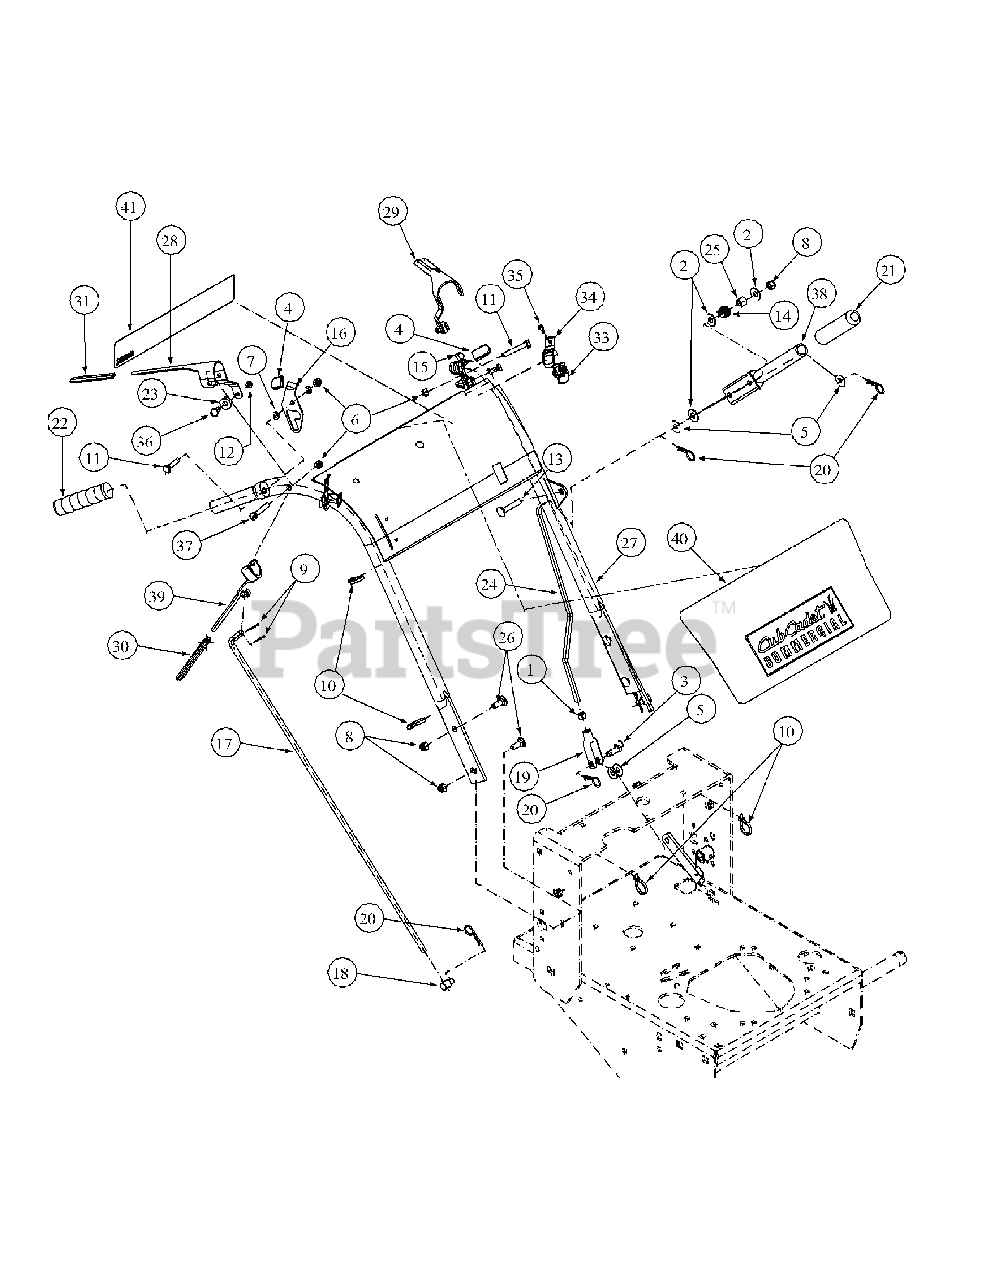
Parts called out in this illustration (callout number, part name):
1	Hex Nut, 3/8-16
2	Flat Washer, 3/8 Zinc
3	Clevis Pin, 3/8 x 1-1/8 Zinc
4	Grip, Neutral Latch, 1.25"
5	Flat Washer, 3/8 Zinc
6	Nylock Nut, 5/16-18
7	Flat Washer, 5/16 Zinc
8	Lock Nut, Nylon Insert, 3/8-16
9	Cotter Pin, 3/32 x 3/4, Zinc
10	Cable Tie, 3/16 x .05 x 7.4
11	Hex Cap Screw, 5/16-18 x 2
12	Lock Nut, Nylon Insert
13	Carriage Bolt, 3/8-16 x 2
14	Spring, .850 OD x 1
15	Neutral Latch, Left Hand
16	Neutral Latch, Right Hand
17	Steering Control Rod
18	Joint Swivel
19	Yoke, 3/8-16 Female
20	Hair Pin 3/8-1/2
21	Handle Grip, Black, 1"
22	Plastic Handle Grip, Black, 4-5/8
23	Control Rod, Hydro Spacer
24	Blade Clutch Rod
25	Spring Sleeve
26	Carriage Bolt, 3/8-16 x 2
27	Handle Assembly
28	Operator Presence Control RH
29	Operator Presence Control LH
30	Control Sleeve, Black
31	Operator Control Sleeve, Yellow
32	Harness Assembly Adapter (not show)
33	Switch Mounting Snap
34	Operator Presence Return Spring
35	Hex Index Washer Screw, 0.500
36	Shoulder Screw, .38 x .412, 1/4-28
37	Hex Cap Screw, 5/16-18, 2.00
38	Blade Clutch Lever
39	Lever Assembly Control
40	Label Commercial Mower Panel
41	Label Commercial Mower Instruction
